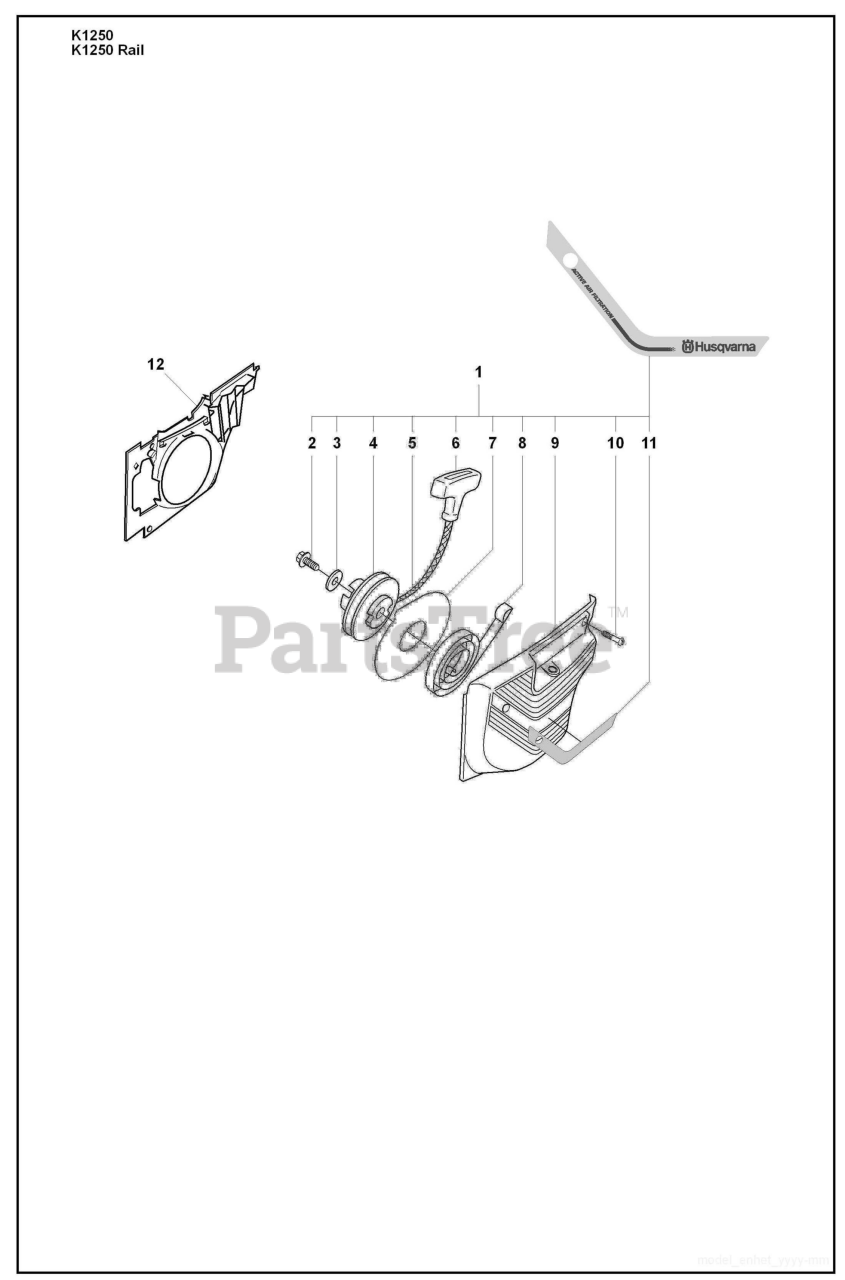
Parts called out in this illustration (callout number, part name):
1	STARTER
2	SCREW
4	STARTER PULLEY
5	STARTER CORD
6	STARTER HANDLE
8	RECOIL SPRING ASSY
9	STARTER COVER
10	SCREW
12	AIR CONDUCTOR
